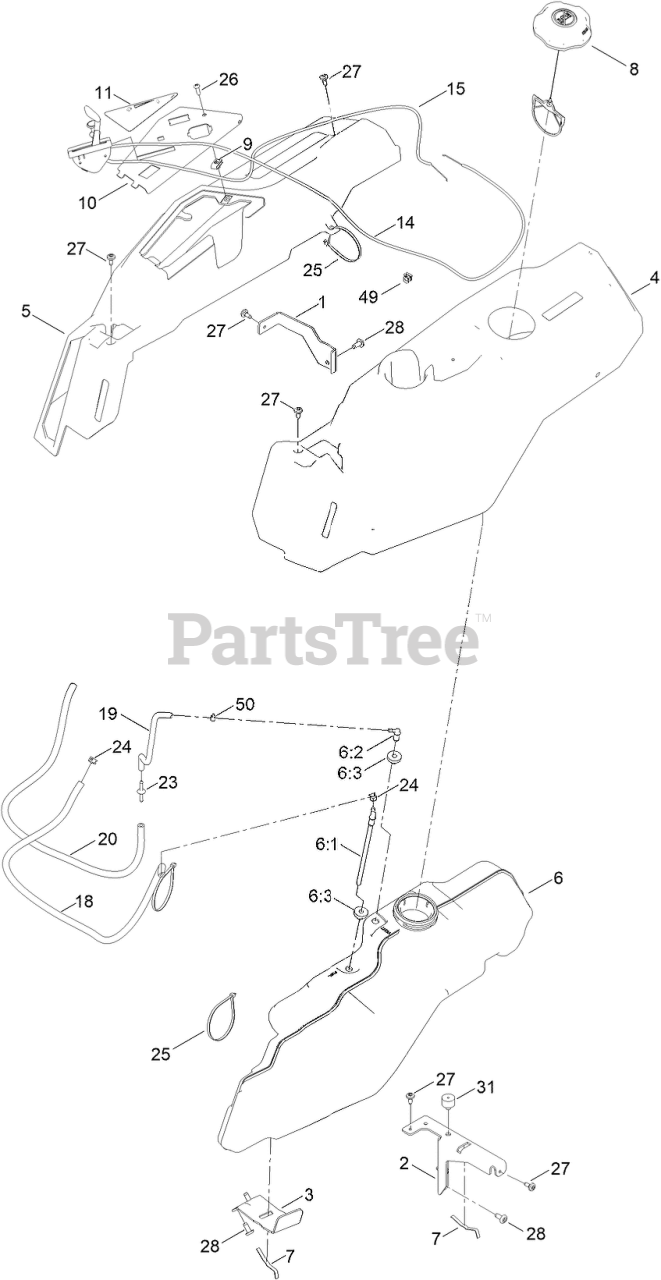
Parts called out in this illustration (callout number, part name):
1	BRACKET-POD
2	SUPPORT-POD, LH
3	SUPPORT-TANK, FUEL
4	POD-LH
5	POD-RH, MYRIDE
6	TANK-FUEL ASM
6:1	CONNECTOR-ELBOW, 90 DEG
6:2	FITTING-ELBOW 90
6:3	BUSHING
7	SPRING
8	CAP-FUEL, RATCHETING
10	PANEL - CONTROL
11	DECAL-PANEL, CONTROL
14	CABLE-THROTTLE
15	CABLE-CHOKE
18	HOSE-FUEL
19	HOSE-FUEL
20	HOSE, FUEL
23	ADAPTER ORIFICE
24	CLAMP-HOSE
25	TIE-CABLE
26	SCREW-PRH
27	SCREW-SHOULDER
31	BUMPER-GROMMET
49	CLIP-HARNESS
50	CLAMP-HOSE
